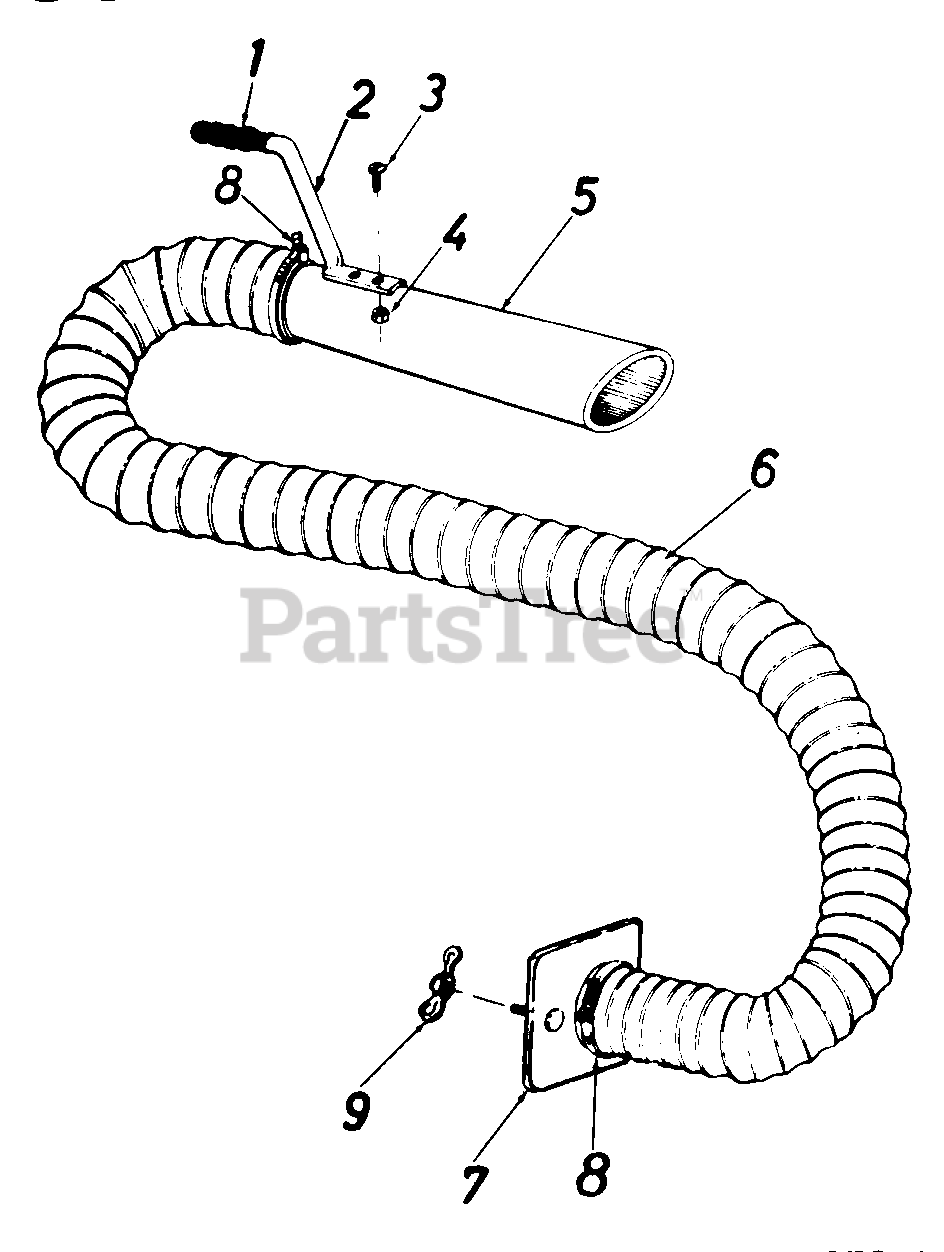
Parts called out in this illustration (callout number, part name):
1	Handle Grip
2	Handle
3	Truss Sems Scr. 10-24 x 1/2" Lg.
4	Hex Nut 10-24 Thd.
5	Hose Nozzle
6	Flexible Hose 4" Dia. x 10' Lg.
7	Hose Adapter Plate
8	Hose Clamp - For 4" Dia. Hose
9	Wing Nut 1/4-20 Thd.
